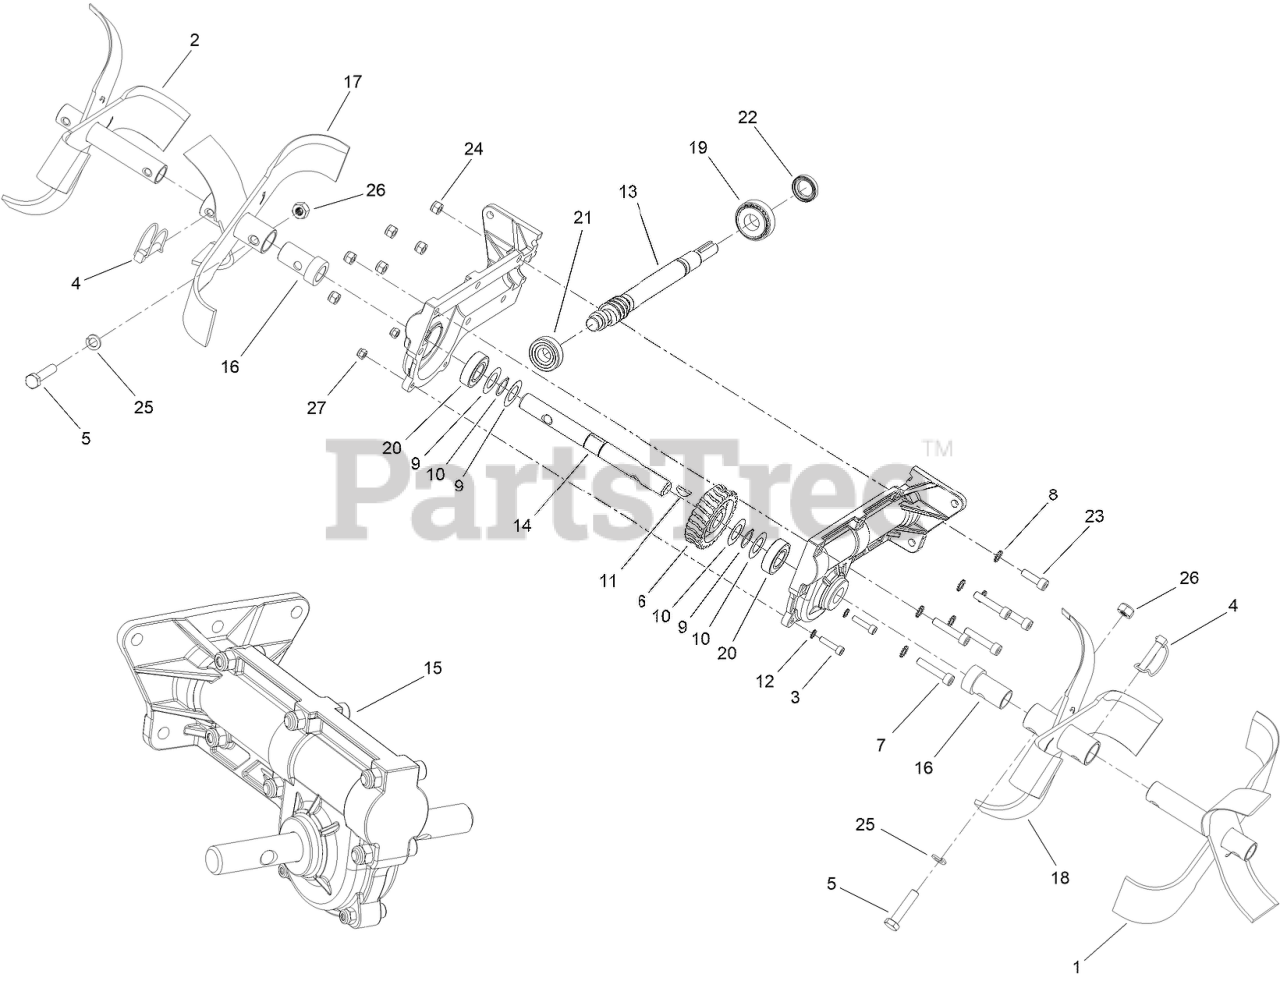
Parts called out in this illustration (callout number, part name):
1	TINE-OUTSIDE LEFT
2	TINE-OUTSIDE RIGHT
3	SCREW-SHCS
4	PIN-CLEVIS, LOCKING
5	SCREW-HHCS
7	SCREW-SHCS
8	WASHER-TOOTH LOCK
9	SPACER-BEARING
10	RING-RETAINING
11	KEY-WOODRUFF
12	WASHER-TOOTH LOCK
13	DRIVE SHAFT
14	TINE SHAFT
15	MOUNT-TRANSMISSION
16	SLEEVE-TINE
17	TINE-INSIDE RIGHT
18	TINE-INSIDE LEFT
19	BEARING-ROLLER
20	BEARING-ROLLER
21	BEARING-ROLLER
22	SEAL-OIL
23	SCREW-SHCS
24	NUT-HEX
25	WASHER-LOCK
26	NUT-HEX
27	NUT-HEX
